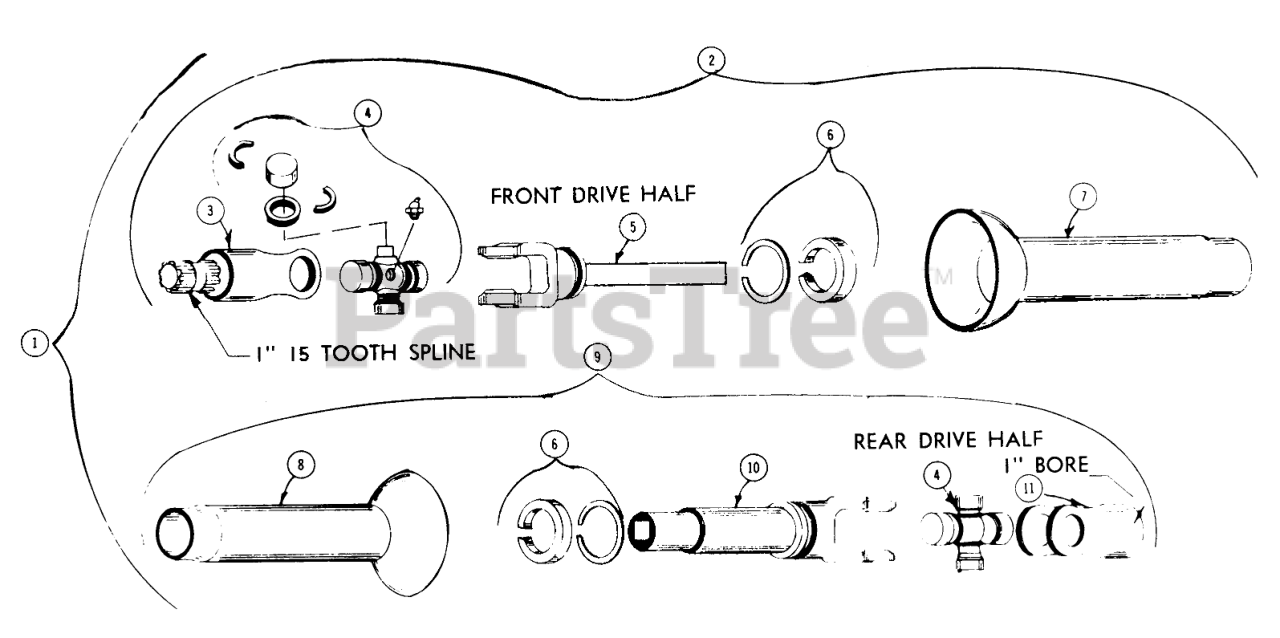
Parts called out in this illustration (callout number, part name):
1	Bottom Pivot Lever
2	Right Hand Pivot Lever, Top
3	1 " Spline Male Yoke
4	Cross Kit Complete (Individual Parts Not Sold Separately)
5	Back Bar
6	Back Bar Plate
7	Outer U Jt. Shield 8" Long
8	Inner U Jt. Shield 8 3/4 Long
9	Left Hand Pivot Lever, Top
10	9 1/2 Long Tubular Shaft & Weld Weld Yoke
11	1" Straight Bore Yoke
